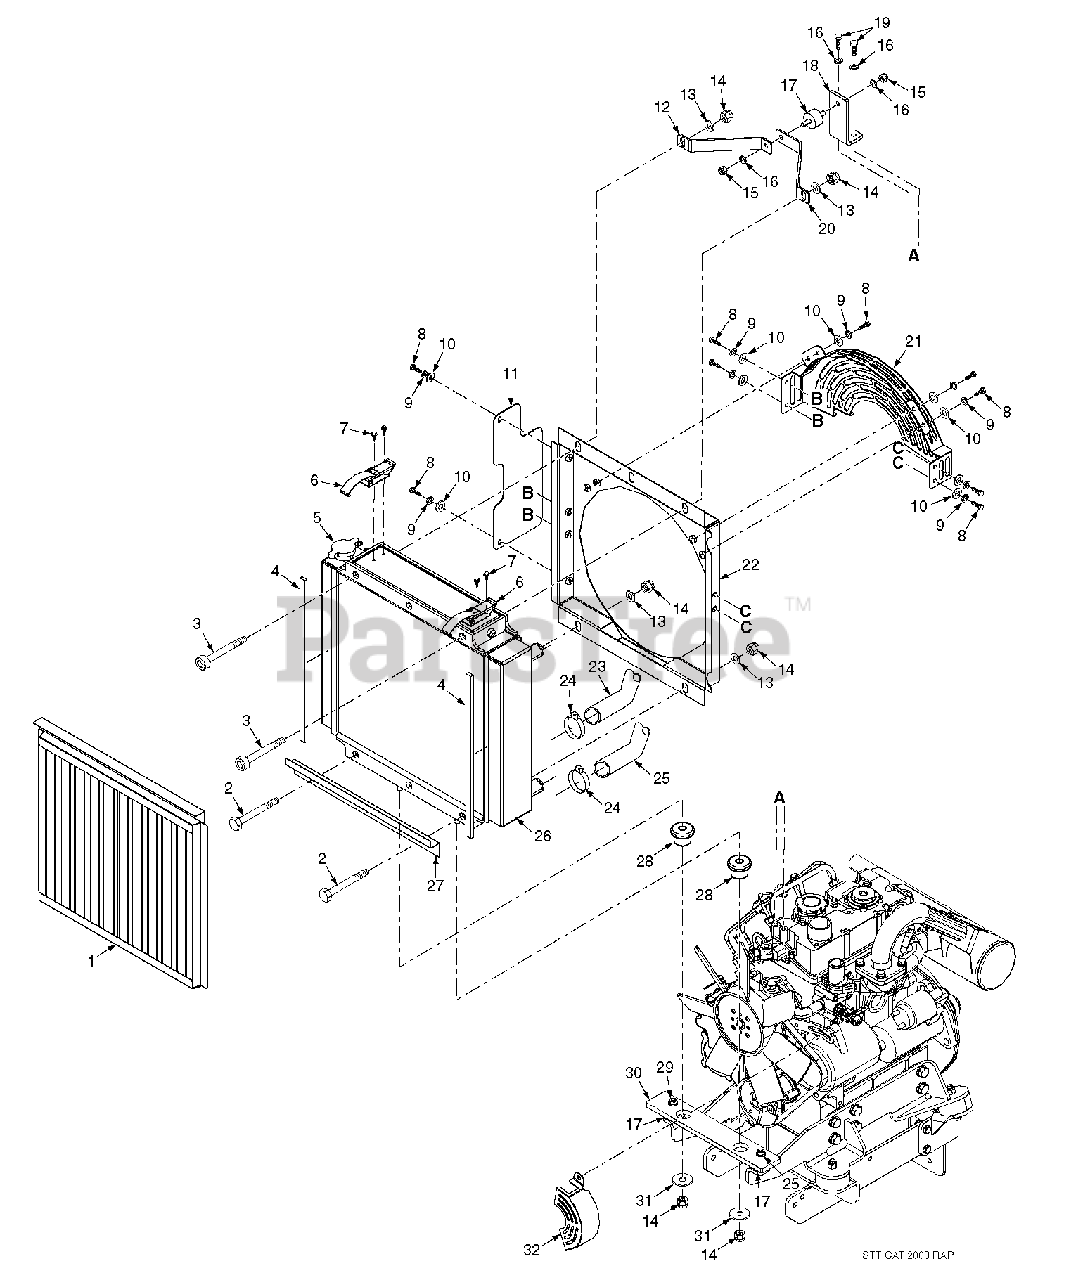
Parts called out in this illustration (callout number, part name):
1	Debris Screen Weldment
2	Bolt, Hex Head 3/8-16 x 4-1/2"
3	Bolt, Socket Head 3/8-16 x 4-1/2"
4	Foam, Seal, 1/2" x 1/4" x 14-1/2"
5	Radiator Cap
6	Latch, Hood
7	Screw, #10-32 x .56
8	Bolt, Hex Head 1/4-20 x .63"
9	Lockwasher, 1/4" Spring
10	Flatwasher, 1/4" (.312 x .750 x .065)
11	Heatshield
12	Bracket, Radiator Mount
13	Flatwasher, 3/8" (.391 x .938 x .105)
14	Nut, Elastic Stop 3/8-16
15	Nut, 5/16-18
16	Lockwasher, 5/16"
17	Mount, Radiator Isolation
18	Bracket, Radiator Mount to Engine
19	Bolt, Hex Head M8 x 1.25 x 25
20	Bracket, Radiator Mount
21	Guard, Fan
22	Shroud Weldment, Radiator
23	Hose, Upper Radiator
24	Clamp, Hose, 1-3/4"
25	Hose, Lower Radiator
26	Radiator
27	Support, Debris Screen
28	Mount, Radiator Isolation
29	Nut, Hex Serrated Flange 5/16-18
30	Mount, Radiator
31	Flatwasher, 3/8" (.406 x 1.50 x 7 ga)
32	Guard, Belt
